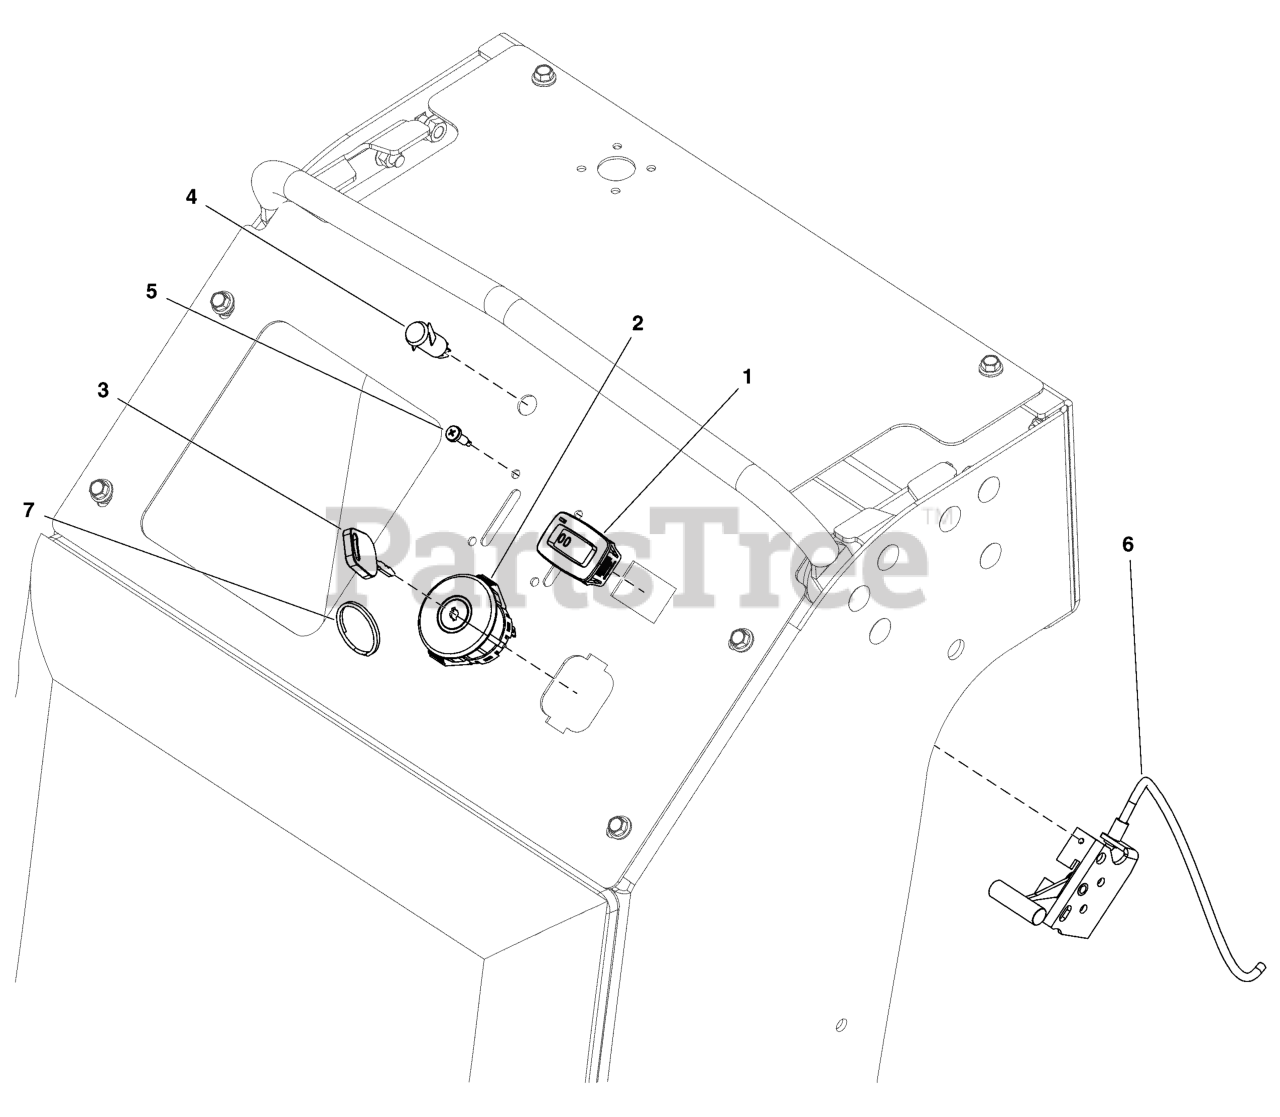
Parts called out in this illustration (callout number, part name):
1	METER, HOUR
2	SWITCH, Ignition
3	KEY-IGNITIOM W/PLASTI
4	LIGHT, INDICATOR
6	CABLE, Throttle/Choke
7	KEY
